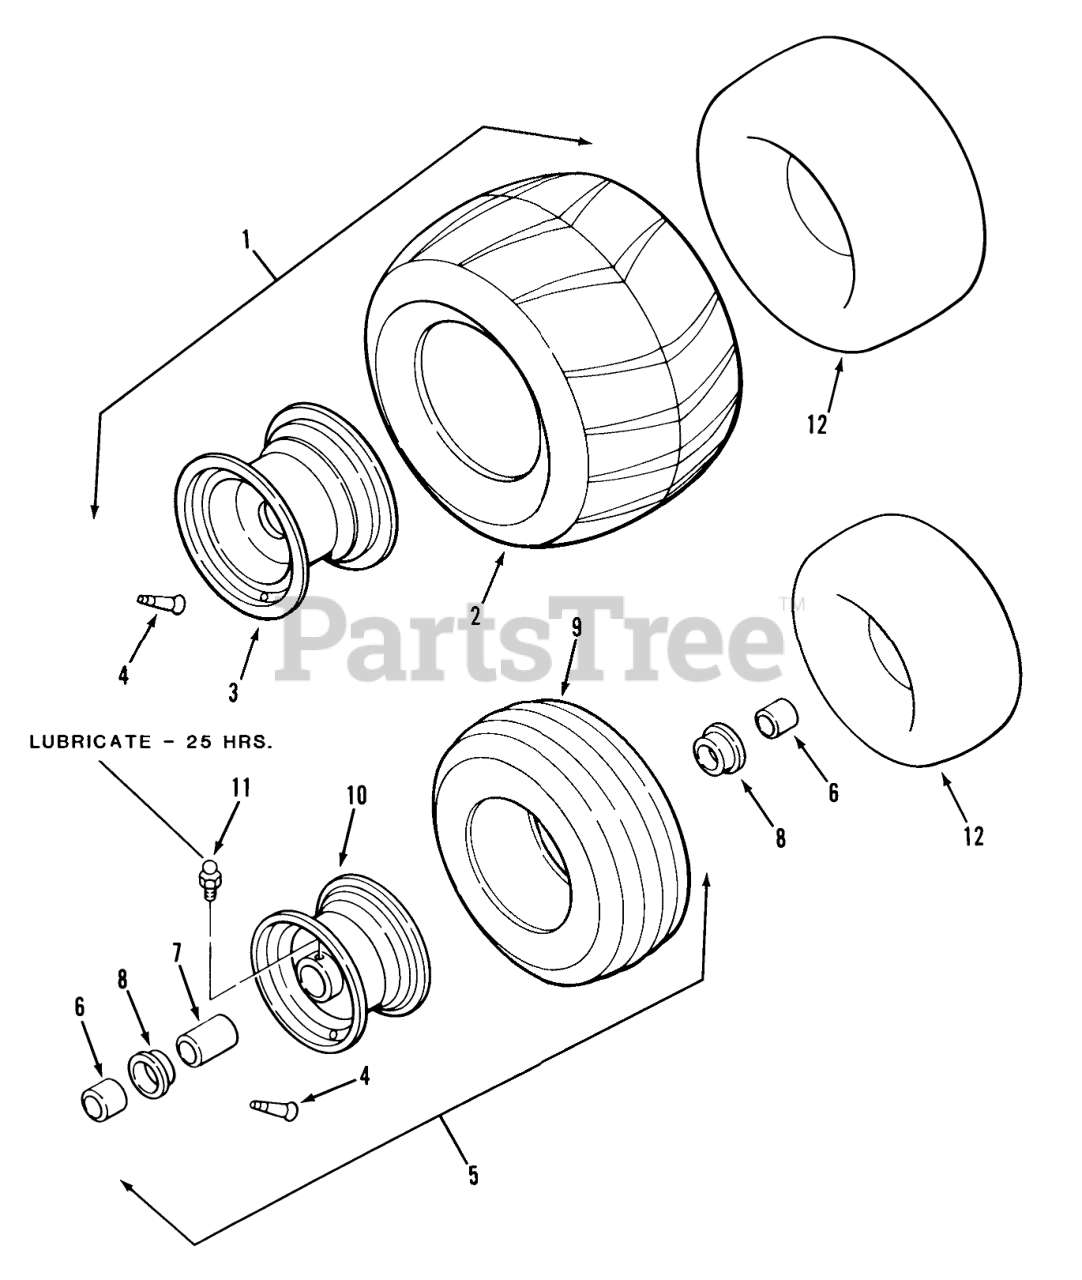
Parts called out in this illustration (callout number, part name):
1	Rear Wheel and Tire 22 x 12.00-8-Knobby (Includes items 2, 3 & 4)
1	Rear Wheel and Tire 22 x 12.00-8-Chevron RH (Includes items 2, 3 & 4)
1	Rear Wheel and Tire 21 x 12.00-8-Chevron LH (Includes items 2, 3 & 4)
2	Rear Tire-Knobby
2	CHEV TIRE 10156-C
3	WHEEL PR SLVR 10238K
4	VALVE
5	Front Wheel and Tire Ass-y (Includes items 7, 8, 9 & 10)
6	Front Wheel Spacer 5/8 x 1
7	SPACER FRT WHEEL INN
8	BEARING BALL
9	Front Tire 13 x 5.00-6
10	WHEEL FT SLUV 10239K
11	Zerk
12	INNER TUBE
12	Tube-Rear
